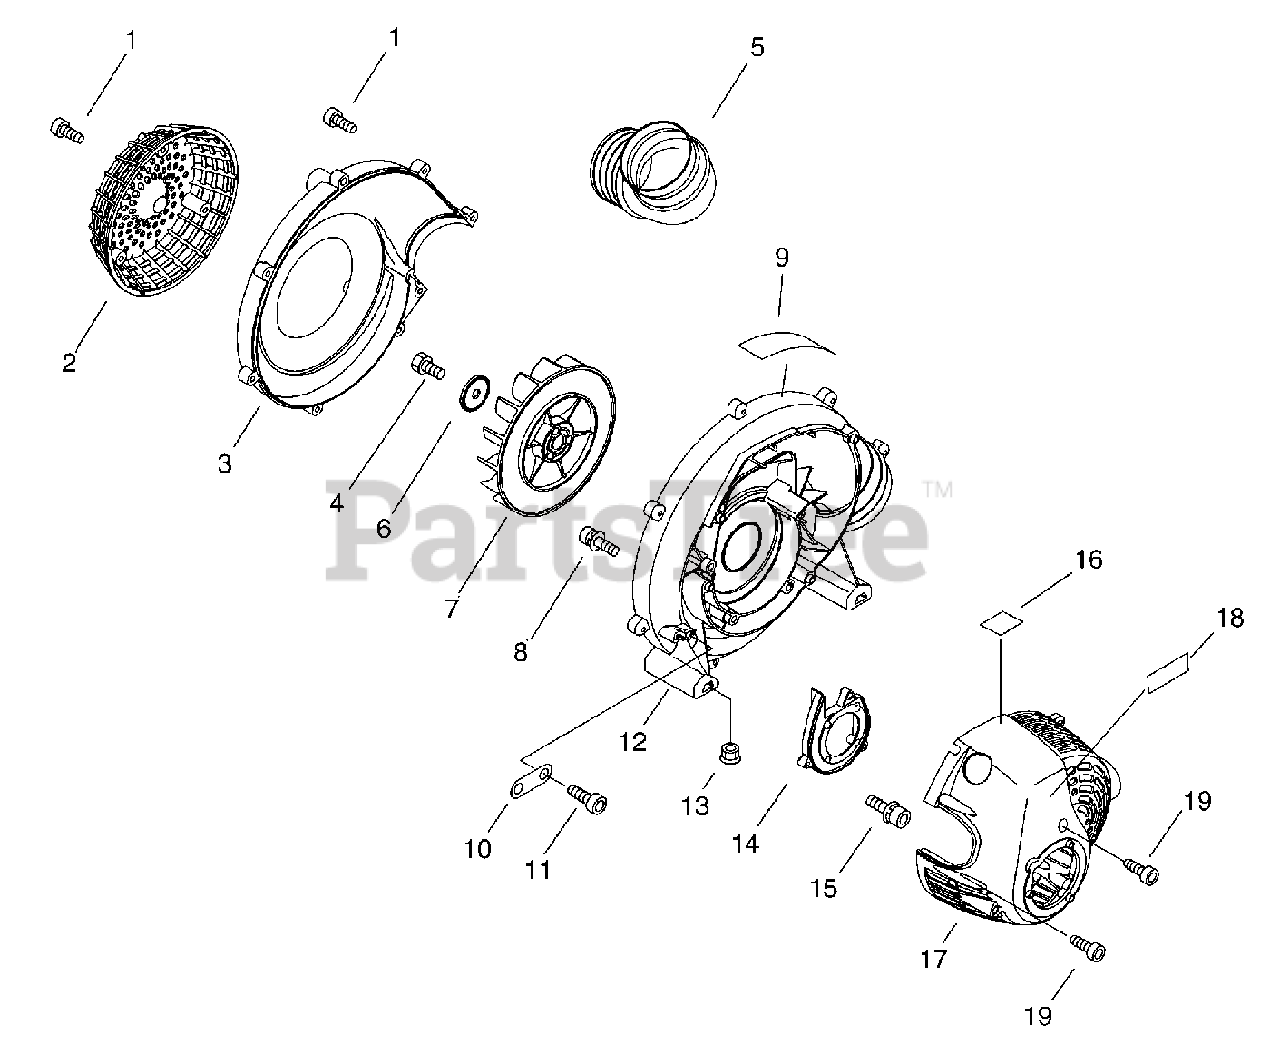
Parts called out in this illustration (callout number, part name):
1	SCREW TAPPING 5×20
2	GUARD, DEBRIS
3	COVER, FAN
4	BOLT 8×14
5	TUBE, BLOWER - ELBOW
6	WASHER 8.2×31×0.8
7	FAN
8	BOLT 4×20
9	LABEL, CAUTION - ISO
10	PLATE, EYE
11	SCREW TAPPING 5×16
12	CASE, FAN
13	NUT, FLANGE M5
15	BOLT 4×16
16	LABEL, CAUTION - HOT
17	COVER, ENGINE
18	LABEL - MODEL PB-265LN
19	SCREW TAPPING 5×16
